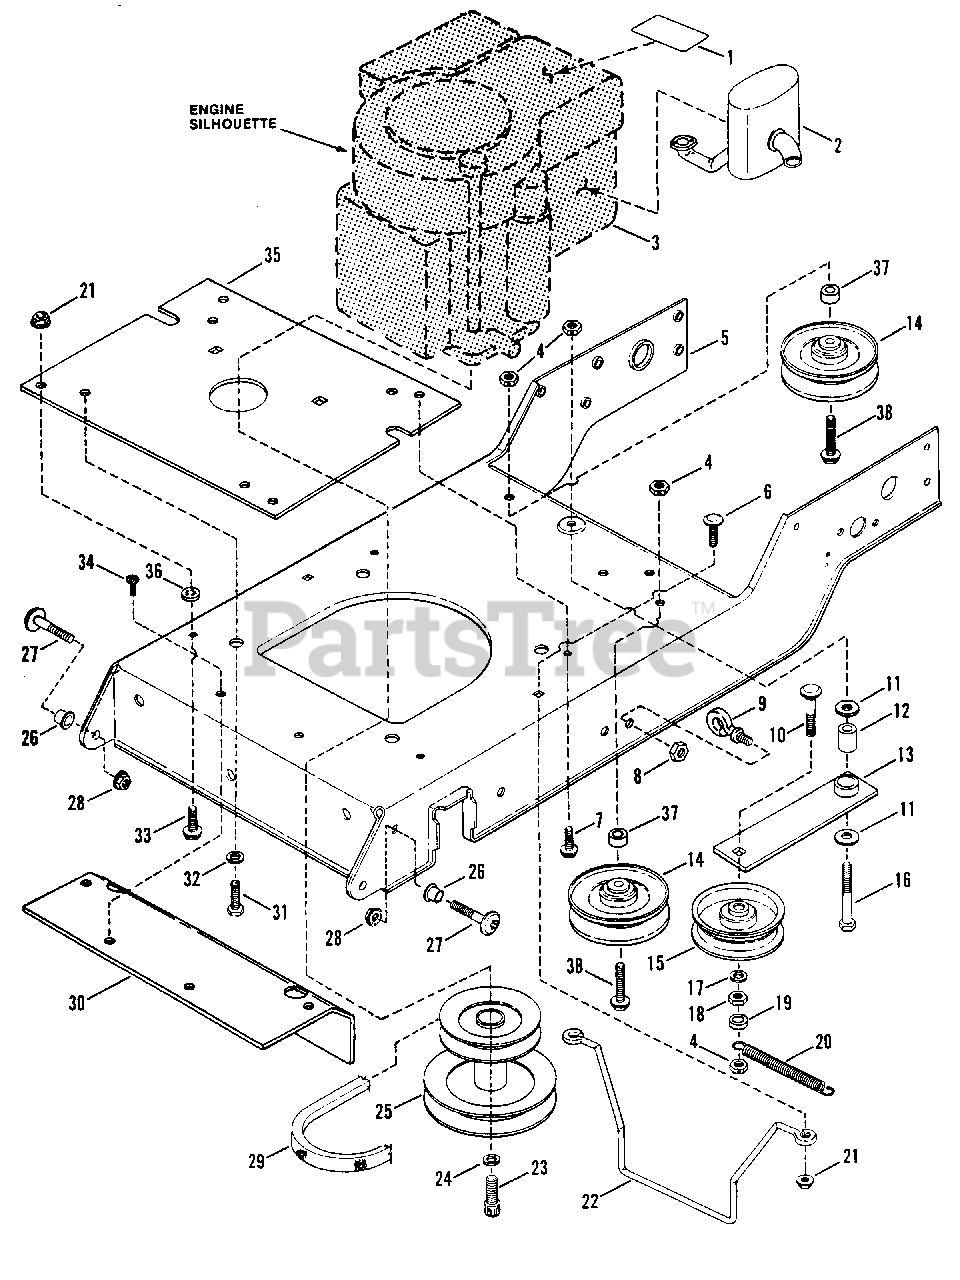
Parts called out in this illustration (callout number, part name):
1	DECAL, Engine 14 HP OHV
2	MUFFLER, Exhaust
4	NUT, 3/8-16 Hex, Center Lock
5	BASE, Engine Kohler
6	BOLT, 5/16-18 x 3/4" Short Neck Carriage
7	BOLT, 5/16-18 x 3/4" Flange Lock
8	NUT, 5/16-18 Hex Lock
9	EYE-BOLT
10	BOLT, 3/8-16 x 2 1/2" Short Neck Carriage
11	WASHER, 3/8" Flat
12	BUSHING, Idler Arm .750 OD x .406 ID x .25 L
13	ARM, Idler
14	PULLEY, Idler, 4" O.D.
15	PULLEY, Idler, 3 3/4" O.D.
16	BOLT, 3/8-16 x 2 1/4 Hex
17	WASHER, 3/8 Split Lock
18	NUT, 3/8-16 Hex
19	SPACER .623 OD x .38 ID x .25 L
20	SPRING, Idler Arm
21	NUT, 5/16-18 Hex Flange Lock
22	GUIDE, Belt
23	SCREW, 7/16-20 Socket, Hex Head Cap
24	WASHER, 7/16 Split Lock
25	PULLEY ASSEMBLY, Engine
26	BUSHING
27	SCREW, Shoulder, 3/8-16 x 1 5/8"
28	NUT, 3/8-16 Hex Flange Lock
29	V-BELT, Traction Drive, (111.6" EL) LT140H33, LT140H41, & RLT140H33
30	AXLE SUPPORT (No longer available)
31	BOLT, M8-1.25 x 25MM Hex Head
32	WASHER, 5/16 Split Lock
33	BOLT, 5/16-18 x 1" Hex Flange Lock
34	SCREW, 5/16-18 x 7/8" Truss Head Torx
35	SPACER, Kohler Engine
36	RETAINER 5/16"
37	SPACER .750 x .39 ID x .5 L
38	BOLT, 3/8-16 x 1 3/4" Hex Flange Lock
